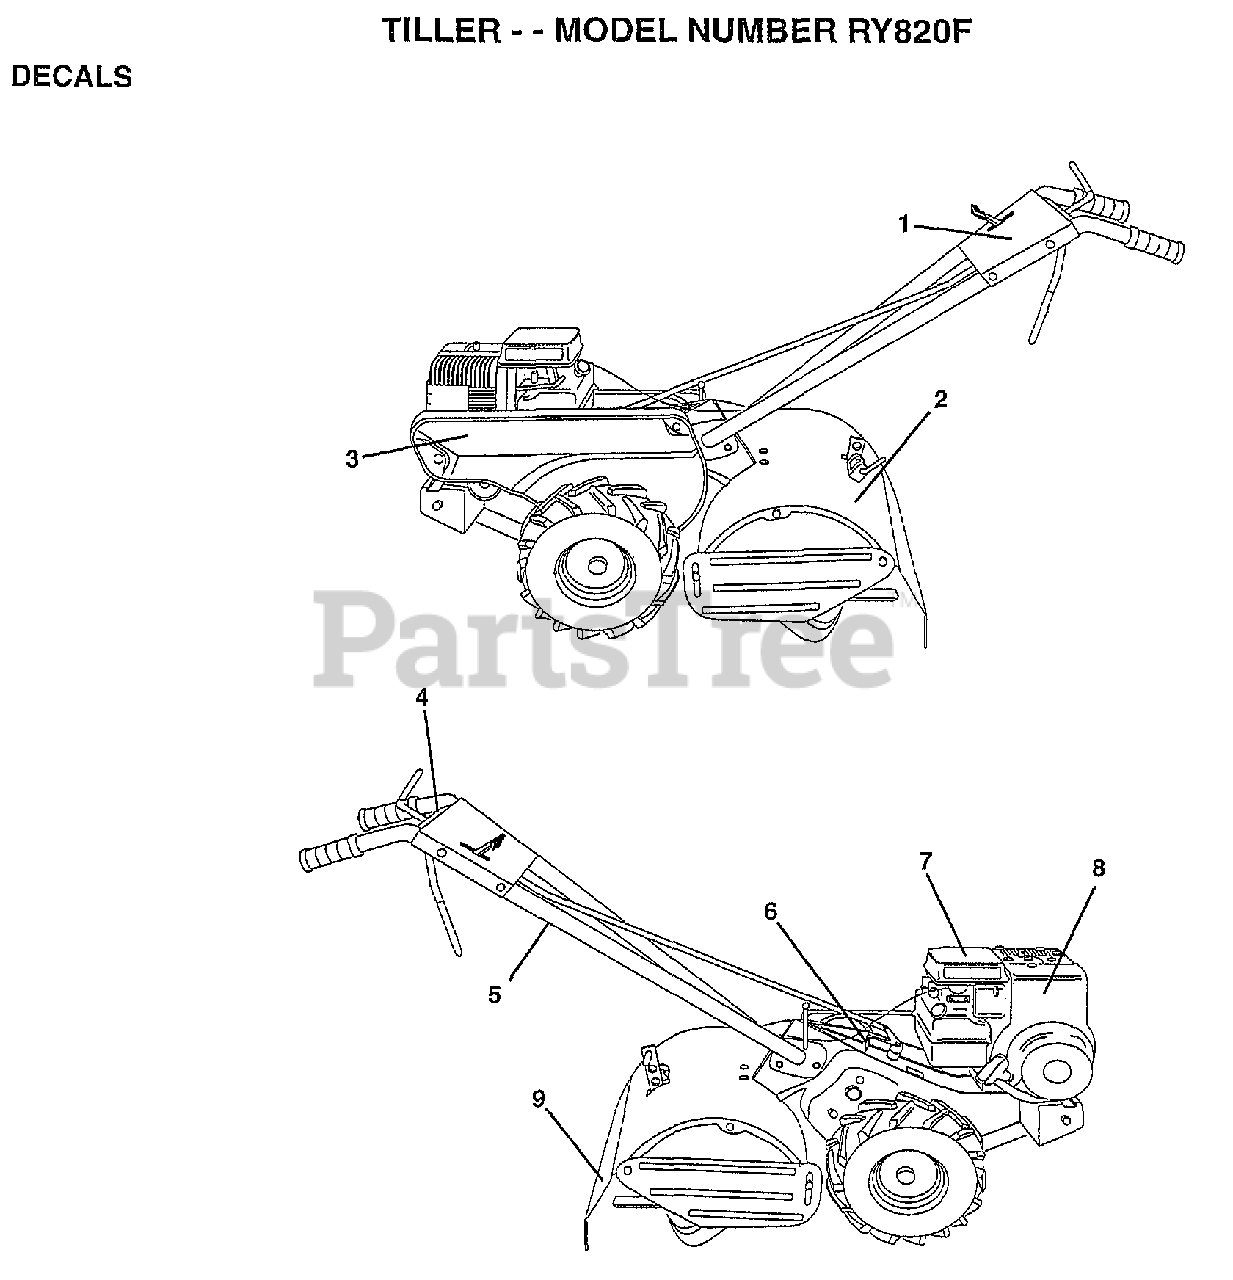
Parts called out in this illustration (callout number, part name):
3	DECAL, LOGO
5	DECAL TI
7	DECAL TI
8	DECAL, BRIGGS & STRATTON
